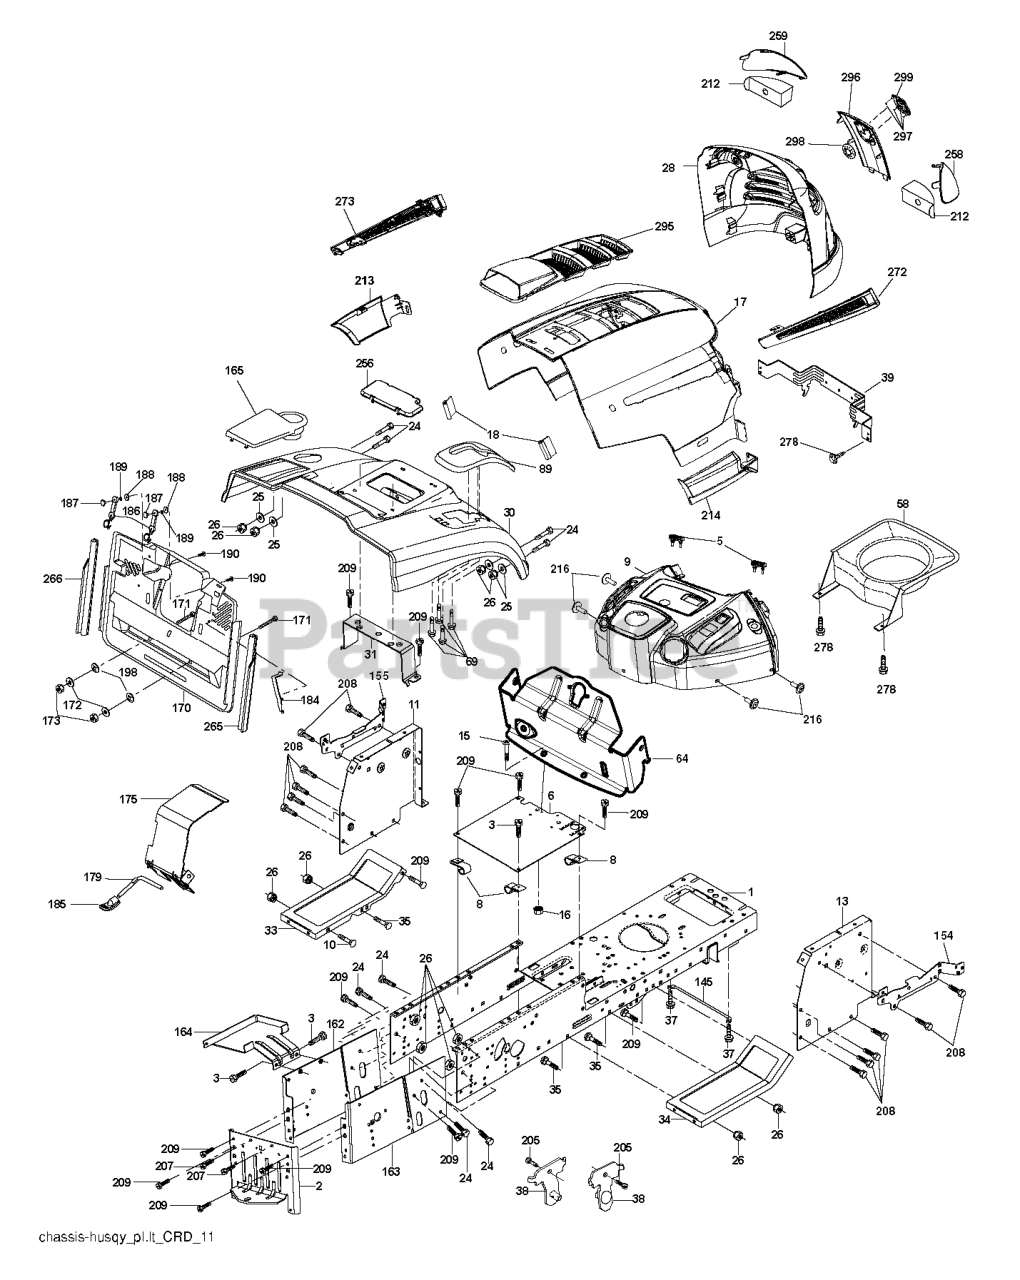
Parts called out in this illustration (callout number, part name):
2	DRAWBAR
3	SCREW 3/8-16X3/4
5	BUMPER DASH
6	PLATE
8	CLIP,INSULATOR
10	BOLT D
11	PANEL.DASH.LH.LTX
13	PANEL ASM, DASH RH
15	Screw, Machine, Truss Head 5/16-18 UNC x 3/4
16	NUT
17	HOOD
18	BUMPER.HOOD.TEX.HUSQVARNA
25	WASHER
26	NUT
28	RP GRILLE/LENS ASM.
30	CONSOLE.CRD.AUTO.GRY
31	BRACKET SUPPORT FENDER
33	FOOTREST PNT LH
34	FOOTREST PNT RH
37	Screw 5/16-18 x 1/2 Hex, Self Tapping 5/16-18 x 1/2
38	BRACKET ASM PIVOT MOWER REAR
39	BRACKET PIVOT
69	SCREW.HI-LO.CONSOLE
89	CONSOLE.CRD.AUTO.GREY.2005
145	ROD PIVOT CHASSIS/HOOD
162	BRACKET
163	BRACKET EXTEN CHASSIS RH CRD
165	RP.COVER.BATTERY.CRD.GREY
172	WASHER
175	DOOR TRAP
179	ROD PIVOT FBI
184	BRACKET.ACTUATOR.BAGGER.SRD
186	LATCH ASSY
187	WELDNUT
189	LOCKWASHER #10
190	SCREW
207	SCREW, 5/16-18 X 1/2
208	SCREW 3/8-16X1/2
209	SCREW, 3/8-16X3/4
212	INSERT REFLECTIVE
213	SKIRT SIDE LH
214	SKIRT SIDE RH
216	SCREW HEXWSHR 1/4-20X3/4
256	COVER FENDER CRD
258	LENS.HUSQVARNA LT.RH
259	LENS.HUSQVARNA LT.RH
265	SEALING
266	SEALING
278	SCREW
295	VENT TOP HOOD
296	TRIM
297	CLIP.RETAINER.TINNER.
298	NUT PUSH M
299	RP LOGO
